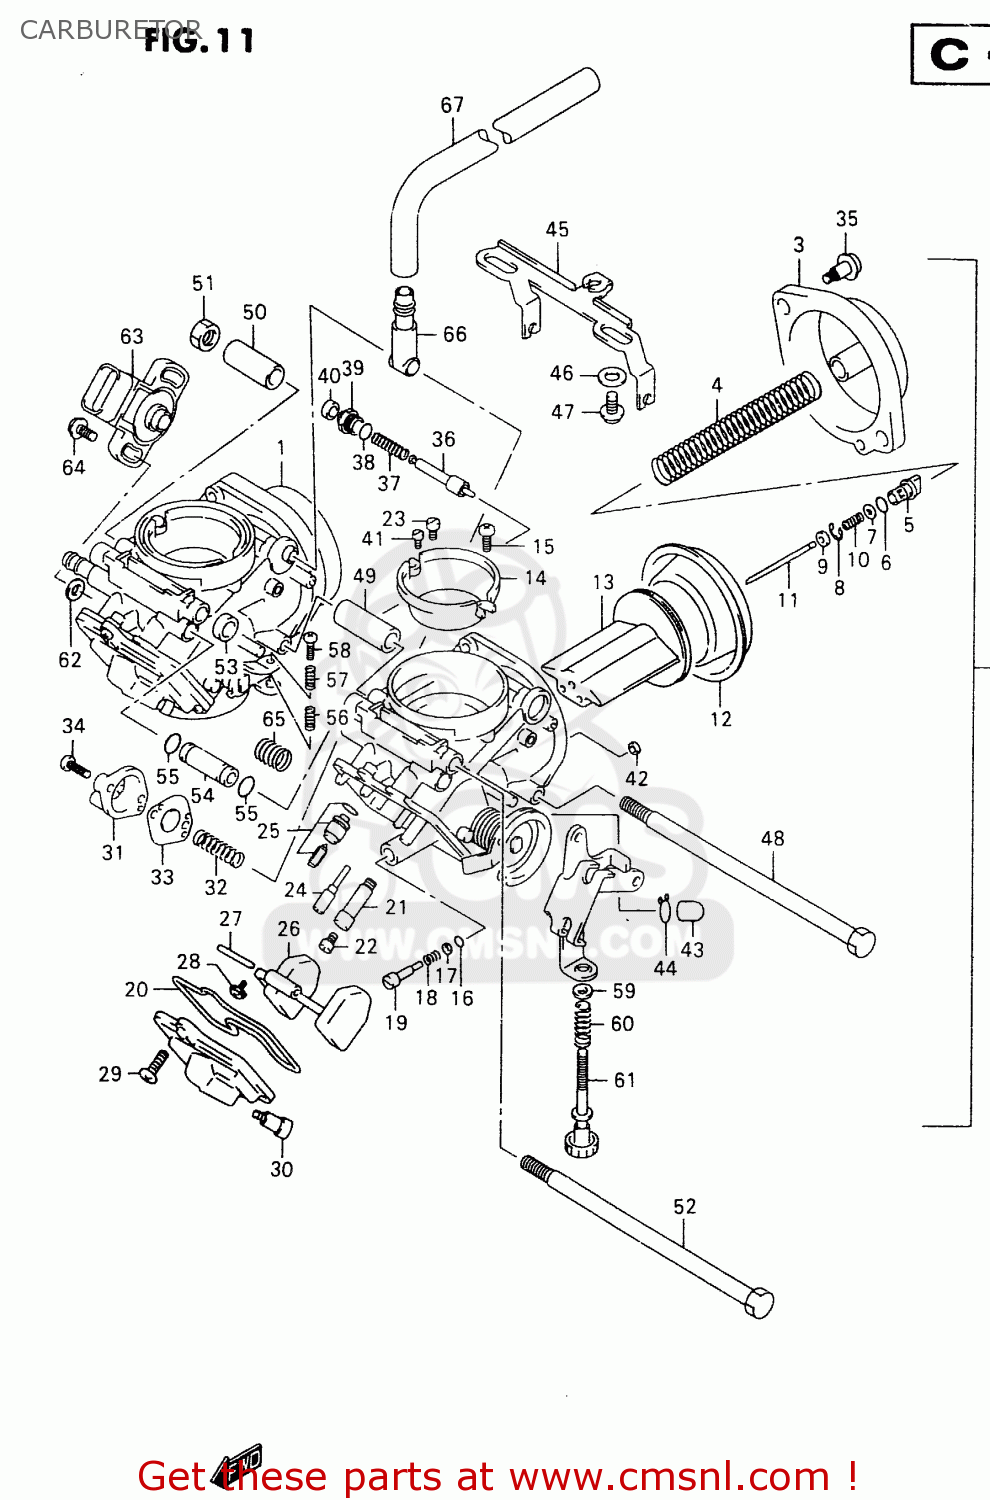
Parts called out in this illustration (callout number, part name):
1	CARBURETOR ASSY, RH
2	CARBURETOR ASSY, LH
3	COVER ASSY,DIAPHRAGM
4	SPRING
5	HOLDER
6	O RING(D:1.9,ID:4.8)
7	WASHER
8	E RING,MULTIPLE JET NOZZLE
9	RING
10	SPRING
11	NEEDLE,JET
12	DIAPHRAGM
13	VALVE,PISTON
14	FUNNEL
15	SCREW
16	O RING,PILOT AIR SCREW
17	WASHER
18	SPRING,THROTTLE SCREW
19	ADJUSTER
20	O RING
21	HOLDER,JET
22	JET,MAIN(110)
23	JET,MAIN(55)
24	JET,PILOT(32.5)
25	VALVE ASSY,NEEDLE(NI)
26	FLOAT ASSY
27	PIN,FLOAT
28	SCREW
29	SCREW
30	SCREW,DRAIN
31	COVER ASSY
32	SPRING
33	DIAPHRAGM ASSY
34	SCREW
35	SCREW
36	PLUNGER
37	SPRING
38	O RING
39	GUIDE SCREW,PLUNGER
40	CAP,STARTER VALVE
41	JET,PILOT AIR(1.9)
42	O RING
43	CAP
44	CLIP
45	LEVER
46	PACKING
47	SCREW
48	BOLT
49	PIPE
50	PIPE
51	NUT
52	BOLT
53	PIPE
54	PIPE
55	O RING
56	SPRING,THROTTLE SCREW
57	SPRING
58	SCREW
59	WASHER
60	SPRING
61	SCREW,ADJUST
62	GASKET,THRO VALVE INSPECTION (NAS)
63	SENSOR ASSY,THROTTLE
64	SCREW, SENSOR
65	SPRING
66	HOSE
67	HOSE
